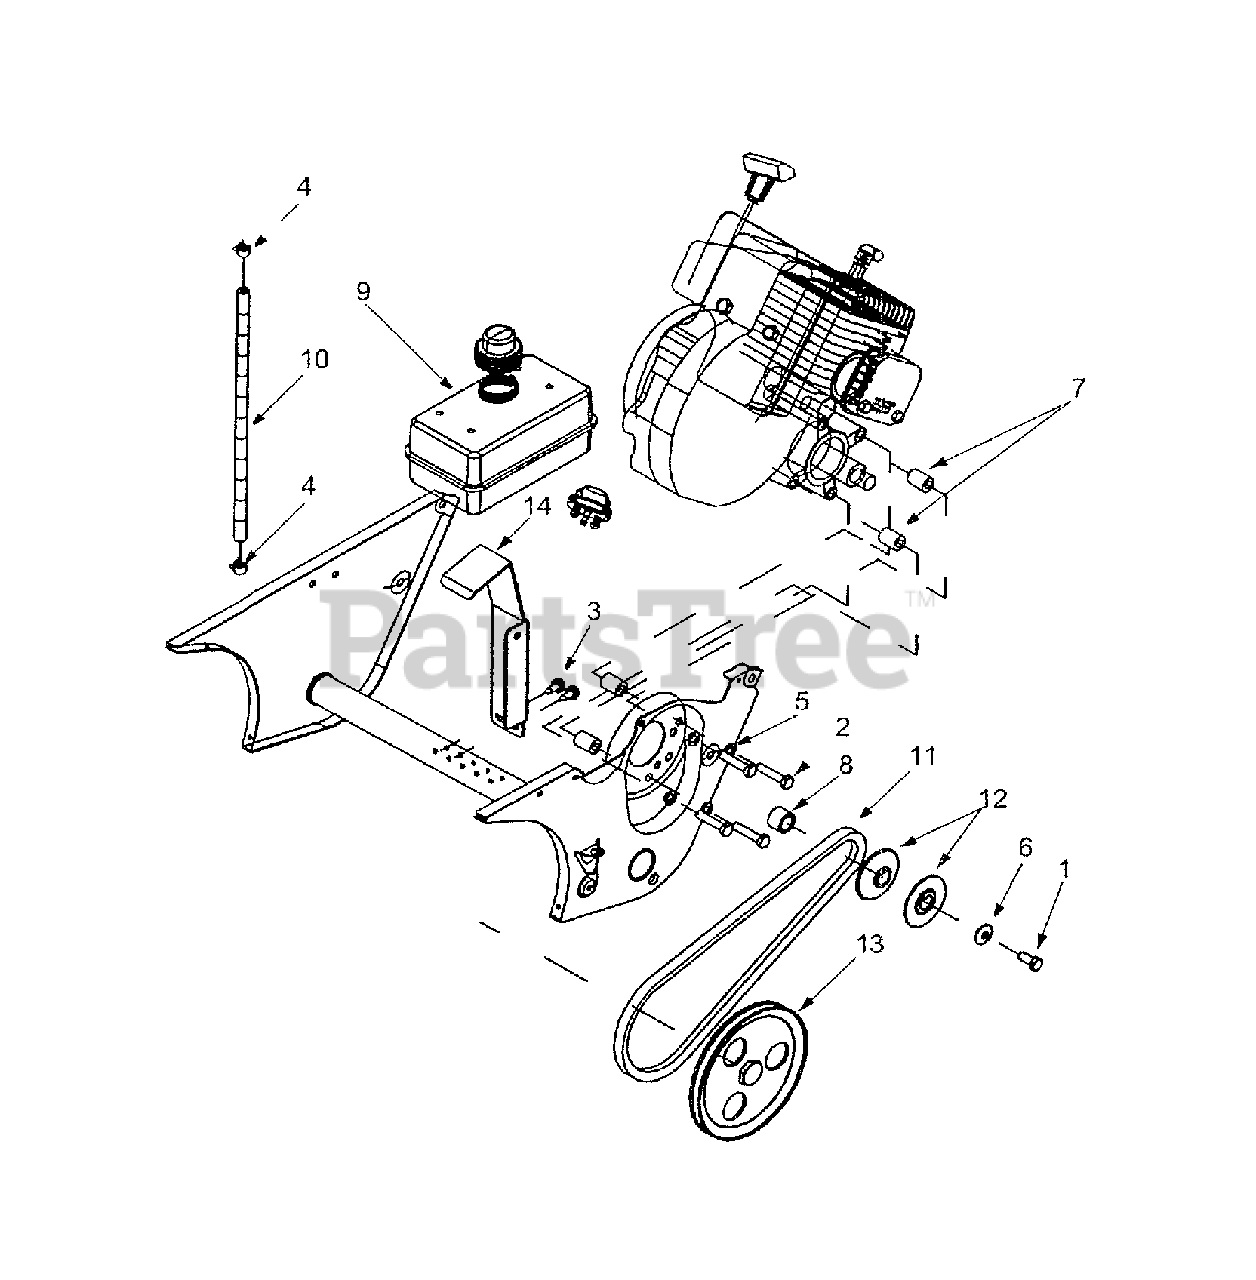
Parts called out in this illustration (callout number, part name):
1	Hex Screw 5/16-24 x 0.75"
2	Hex Screw 5/16-18 x 1.5"
3	Self-Tapping Screw 1/4-20 x .625"
4	Hose Clamp
5	Lock Washer
6	Beleville Washer
7	Spacer
8	Spacer
9	Gas Tank: 1 quart
10	Fuel Line Hose
11	V-Belt
12	V-Pulley Half
